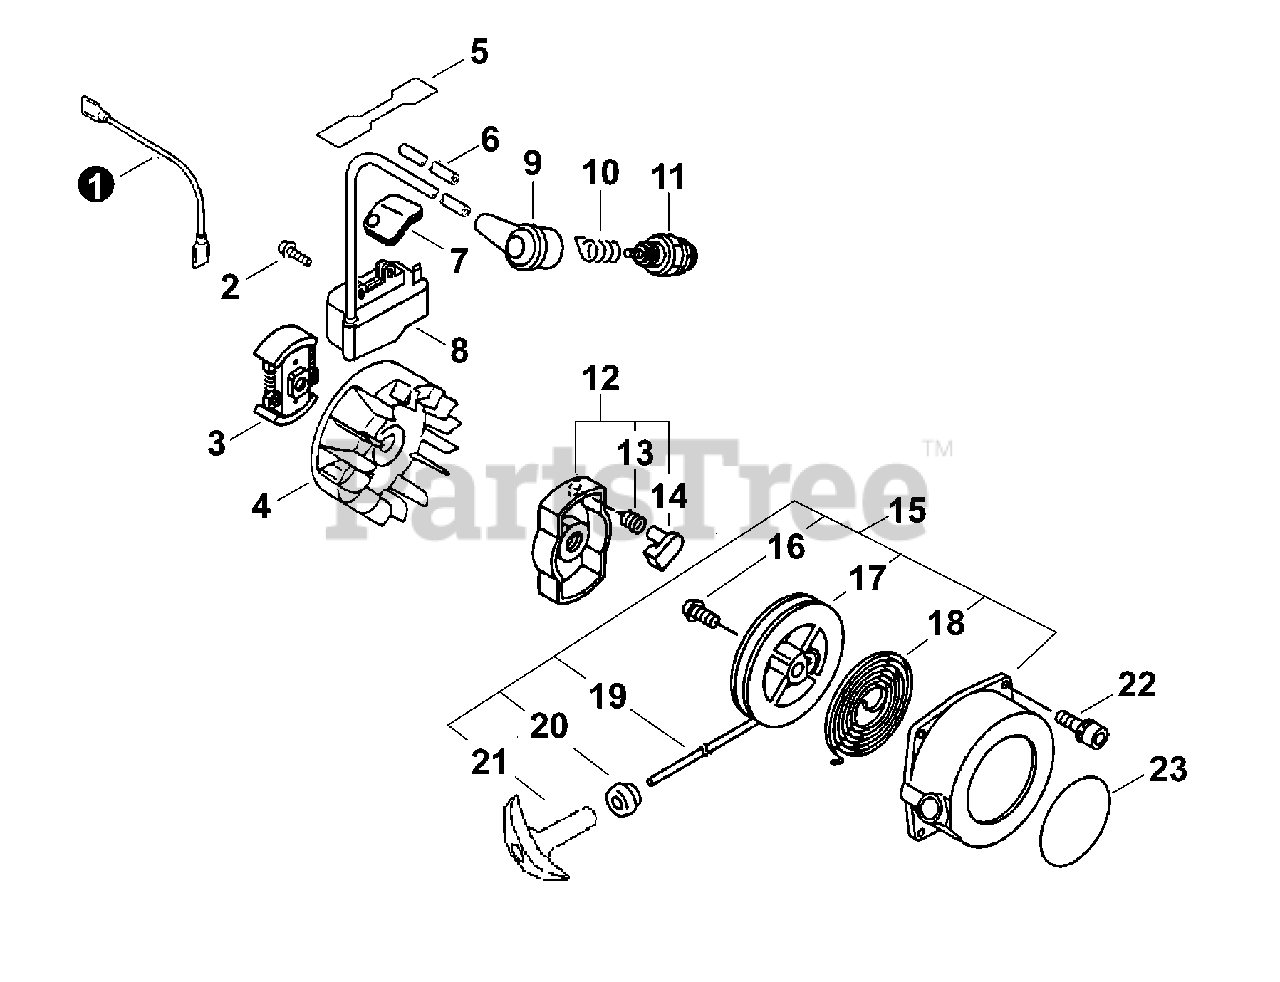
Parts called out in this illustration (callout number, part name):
1	LEAD - GROUND
2	SCREW - 4×20
3	CLUTCH ASY
4	FLYWHEEL
5	LABEL - SPARK PLUG -- BPM8Y
6	TUBE, INSULATOR
8	COIL, IGNITION
9	CAP, SPARK PLUG
10	TERMINAL, SPARK PLUG CAP
11	SPARK PLUG -- BPM8Y
12	STARTER PAWL ASY
13	SPRING, RETURN
14	PAWL, STARTER
15	STARTER ASY
16	SCREW
17	REEL, ROPE
18	SPRING, REWIND
19	ROPE, STARTER
20	GUIDE, ROPE
21	GRIP, STARTER
22	SCREW - 4×16
23	LABEL - ECHO
